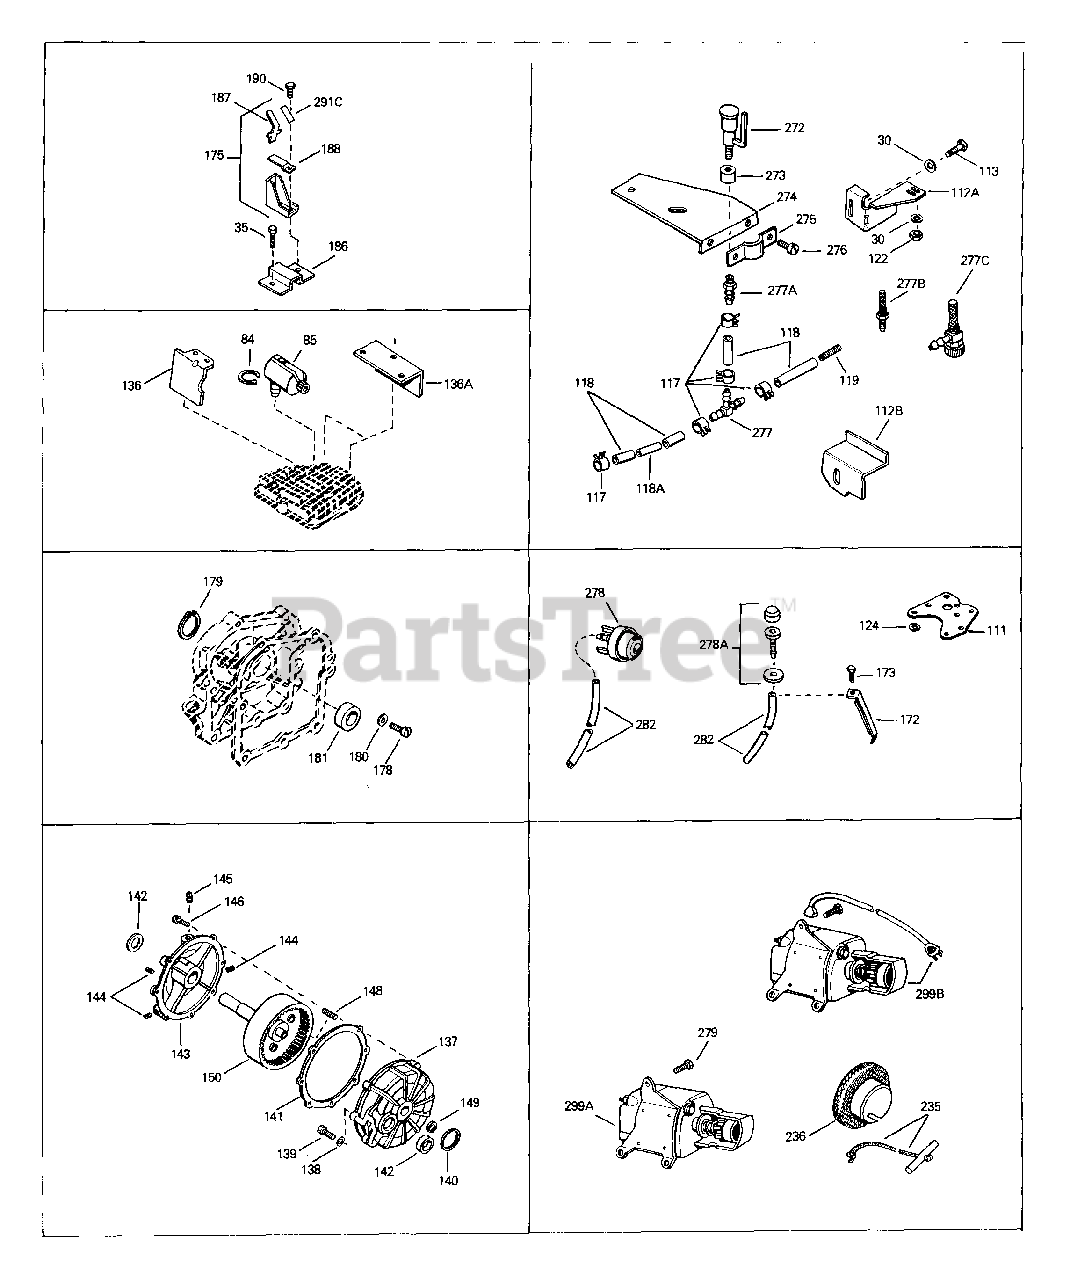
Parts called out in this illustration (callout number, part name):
30	Washer, Flat
35	Screw, Hex flange hd., 5/16-18 x 1-1/ 2
35	Screw, Hex hd., 5/16-18 x 2-3/8
35	Screw, Hex flange hd., 5/16-18 x 2
35	Screw, Hex flange hd., 5/16-18 x 2-1/ 4
35	Screw, Special Hex hd. tapped, 5/16-1 8 x 2
84	Clamp, Wire
85	Cup, Spark plug
113	Screw, Hex washer hd. Durlok, 1/4-20 x 5/8
117	Clamp, Fuel line
118	Line, Fuel (Braided 8.25")
118	Line, Fuel (Braided 16")
118	Line, Fuel (Braided 32")
118	Line, Fuel (Epichlorohydrin 14.5")
122	Nut, Lock, 1/4-20>Spec. Nos. 45133K, 133L,
136A	Baffle, Heat
178	Screw, Hex washer hd. self-tap Sems, 10-24 x
179	Ring, Retaining
180	Washer, Flat
181	Bearing, Ball
299B	Starter Motor (120 volt)
